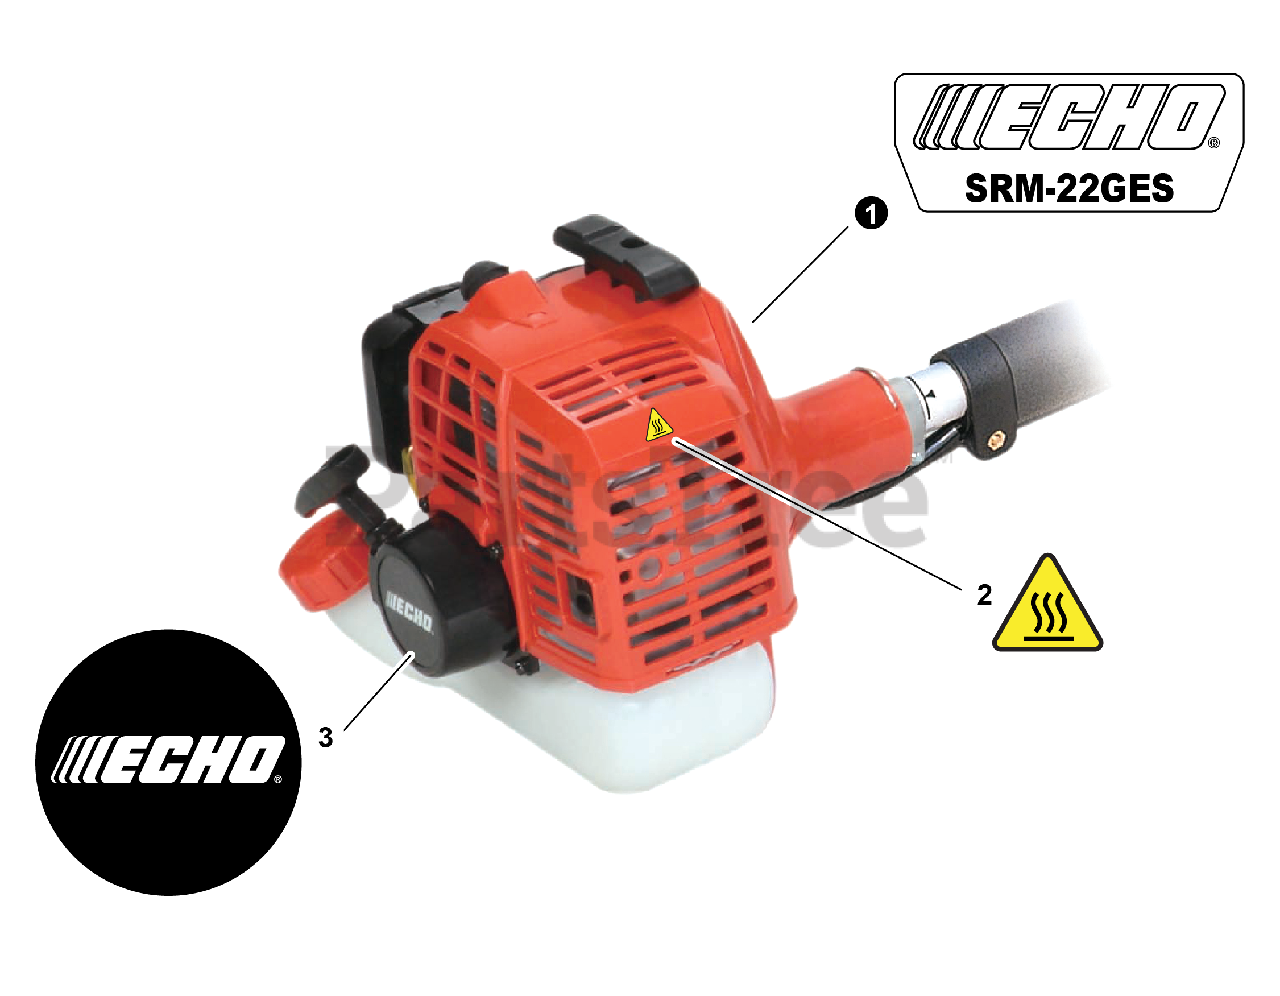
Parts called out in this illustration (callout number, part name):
1	LABEL - SRM-22GES
2	LABEL - CAUTION - HOT
3	LABEL - RECOIL STARTER
